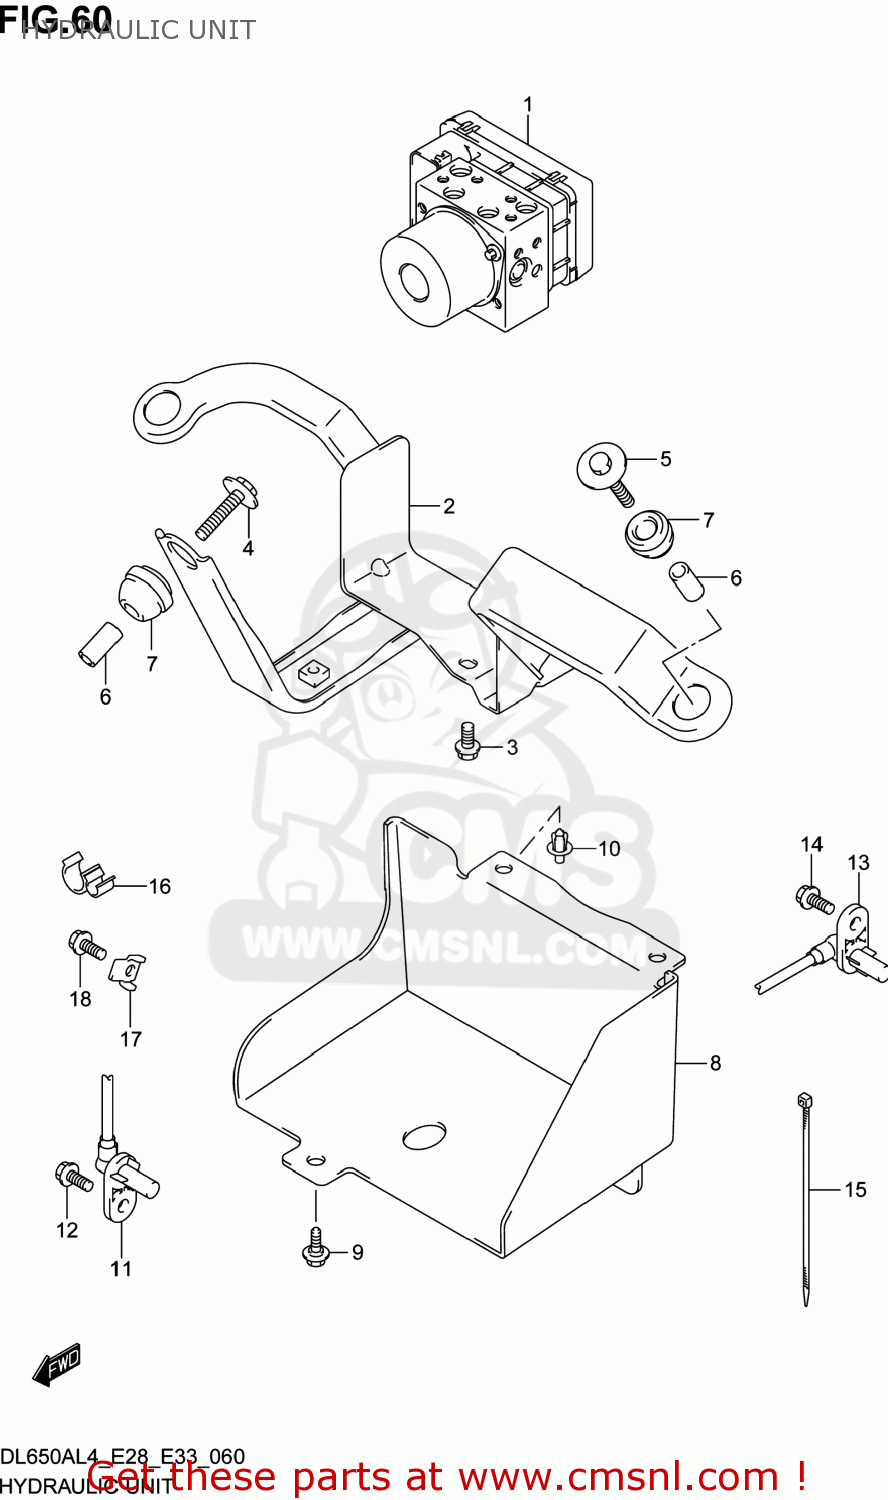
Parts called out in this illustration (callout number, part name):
1	UNIT ASSY,HYDRAULIC ABS
2	HOLDER,HYDRAULIC UNIT ABS
3	BOLT
4	BOLT(6X30)
5	BOLT(6X37)
6	SPACER(6.5X10X20)
7	CUSHION
8	COVER,HYDR ABS UNIT
9	BOLT(6X16)
10	CLIP(BLACK)
11	SENSOR,FR WHEEL ABS
12	BOLT
13	SENSOR,RR WHEEL ABS
14	BOLT
15	CLAMP(L:145)
16	CLAMP
17	GUIDE,SENSOR LEAD
18	BOLT
